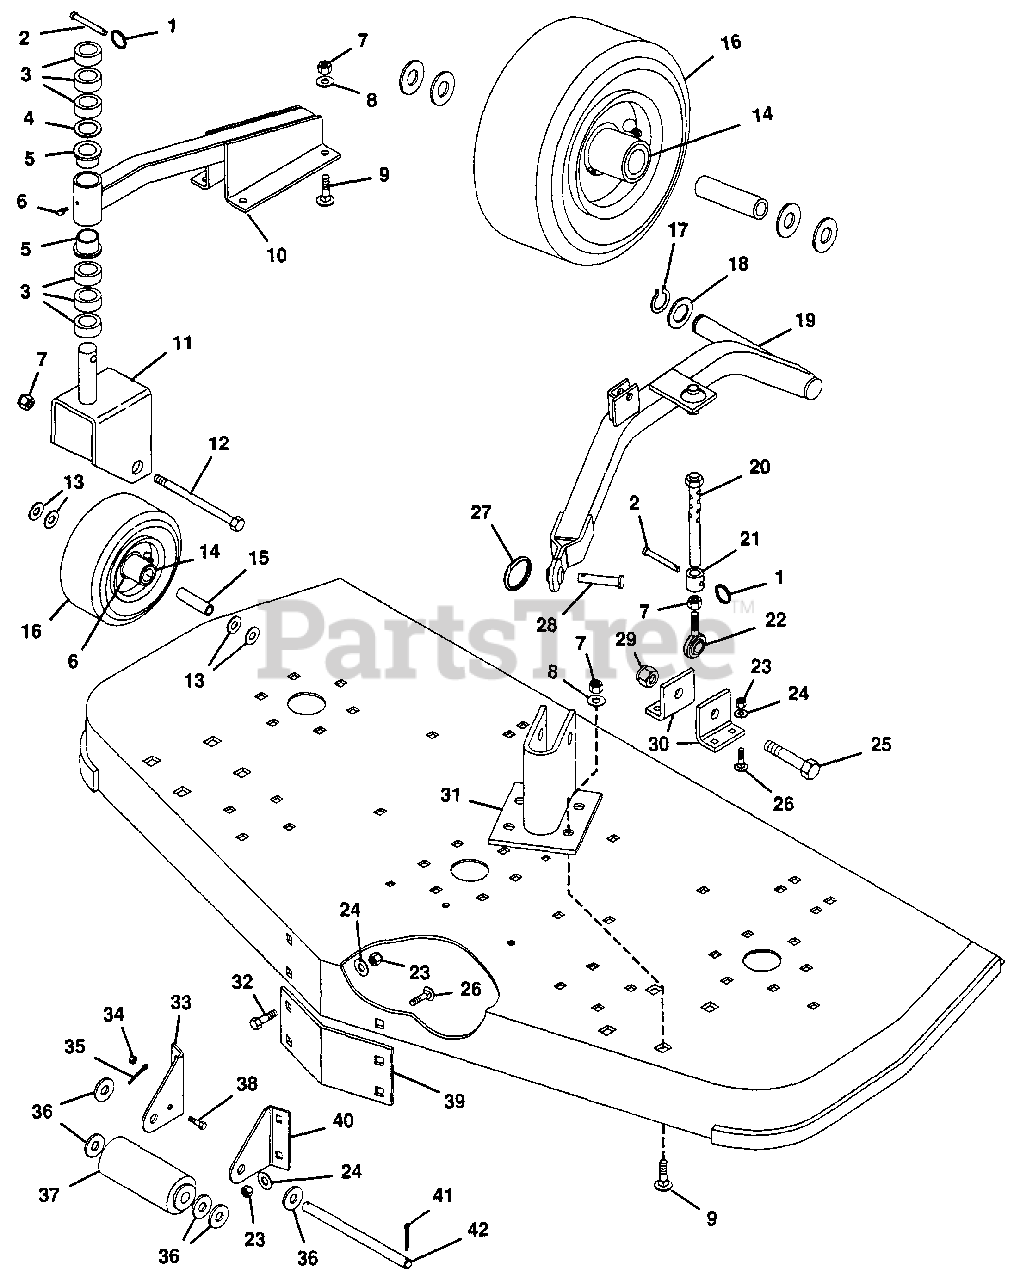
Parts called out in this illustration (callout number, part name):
1	Ring, Split 1.25
2	Pin, Clevis .31x2.25
3	Bush., St. 1.07x1.75x.500 Stl.
4	Race, Bearing Thrust
5	Bush., Flg. 1.03x1.75x.750 Ny.
6	Fitting, Lube 1/4-28
7	Nut, Lock 1/2-13
8	Washer, Flat .531x1.062x.095
9	Bolt, 1/2-13x1.50 Rd Hd Sq Nk
10	Weldment, Caster Wheel Support
11	Weldment, Caster Fork
12	Bolt, Hex 1/2-13x5.50
13	Washer, Flat .531x1.250x.100
14	Bearing, Ball
15	Bush., St. .506x.748x3.34 Stl.
16	Wheel, Gauge
17	Ring, Retaining
18	Bearing, Thrust Race
19	Weldment, Mower Arm L.H.
19	Weldment, Mower Arm R.H.
20	Weldment, Height Adjustment
21	Bush., St. .765x1.25x.910 Stl.
22	Rod, End
23	Nut, Lock 3/8-16
24	Washer, Flat .406x.812x.065
25	Bolt, Hex 3/4-10x3.5
26	Bolt, 3/8-16x1.00 Rd Hd Sq Nk
27	Ring, Split 2.24
28	Pin, Clevis .87x2.40
29	Nut, Lock 3/4-10
30	Bracket, Deck Support Rear
31	Wldmnt, Mwr Mounting Arm Brckt
32	Bolt, Hex 3/8-16x1.00
33	Bracket, Roller R.H.
34	Nut, Lock 1/4-20
35	Pin, Cotter .250x2.00
36	Washer, Flat .656x1.312x.095
37	Roller, Gauge
38	Bolt, Hex 1/4-20x.75
39	Plate, Deck Reinforcement
40	Bracket, Roller L.H.
41	Pin, Cotter .25x1.00
42	Shaft, Center Roller
